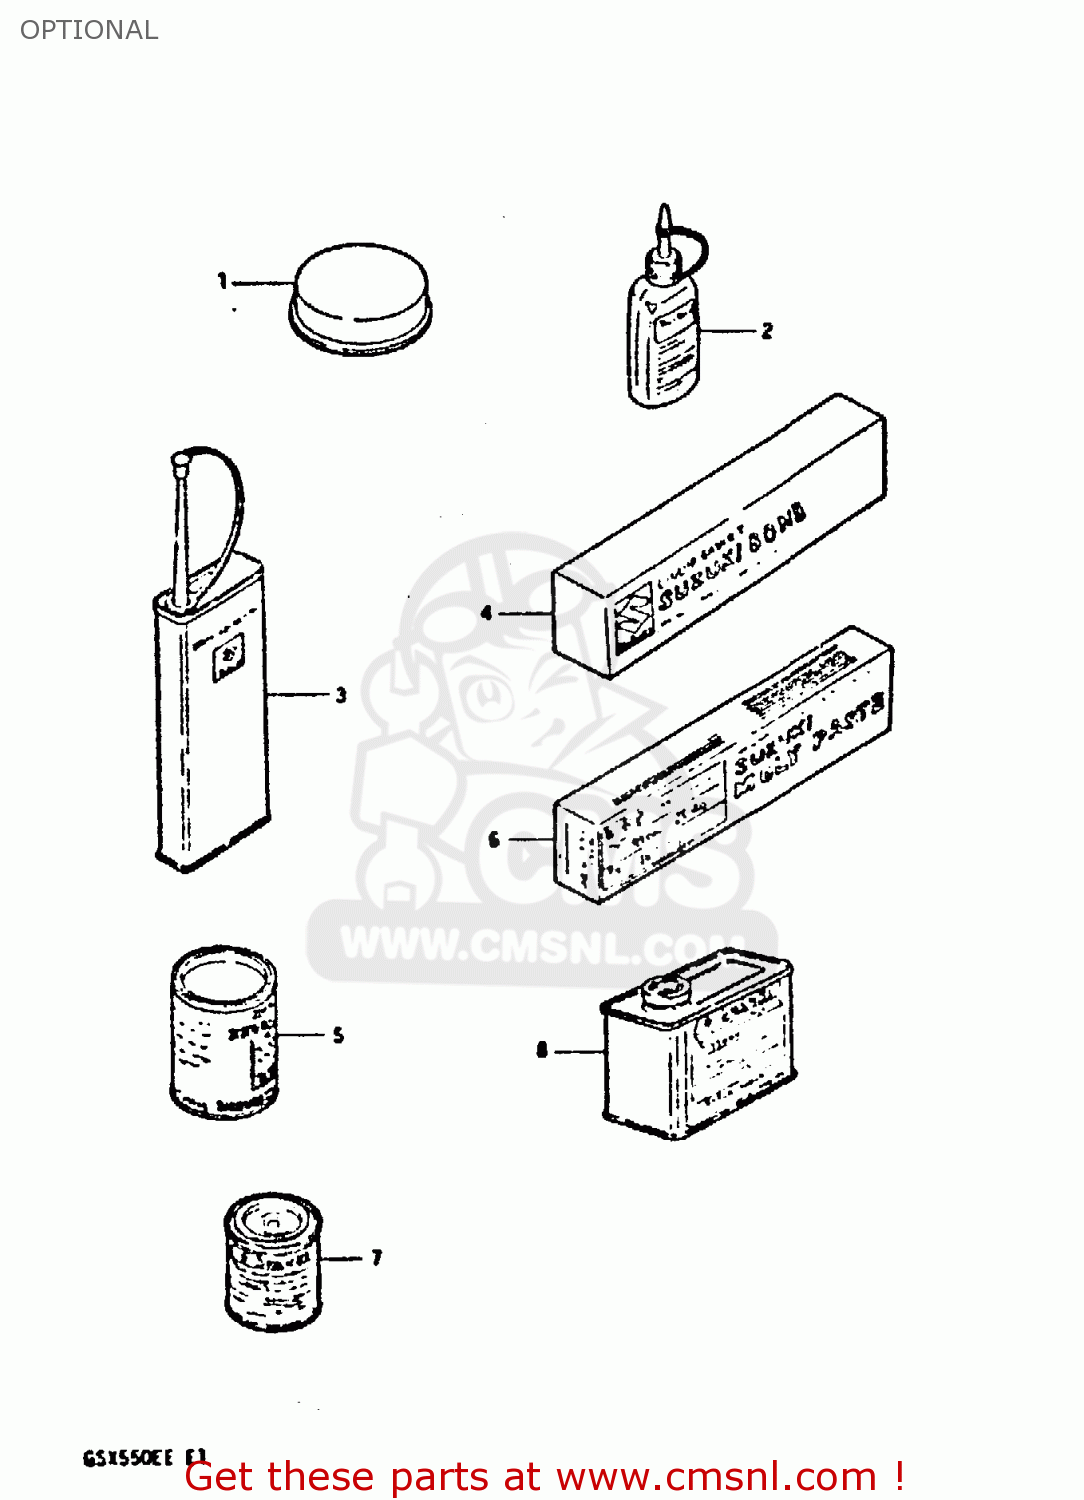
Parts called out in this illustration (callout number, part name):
1	GREASE,PBC FOR BRK PAD 20G
2	THREAD LOCK NO.1342
3	THREAD LOCK NO.1401 CLEAR 200G
4	LIQUID GSKT NO.1207B 100G BLK
5	GREASE(C)EP2 LITHIUM 150G
6	SUZUKI MOLY PASTE
7	PAINT,BLACK
8	PAINT (SPACE BLACK)
